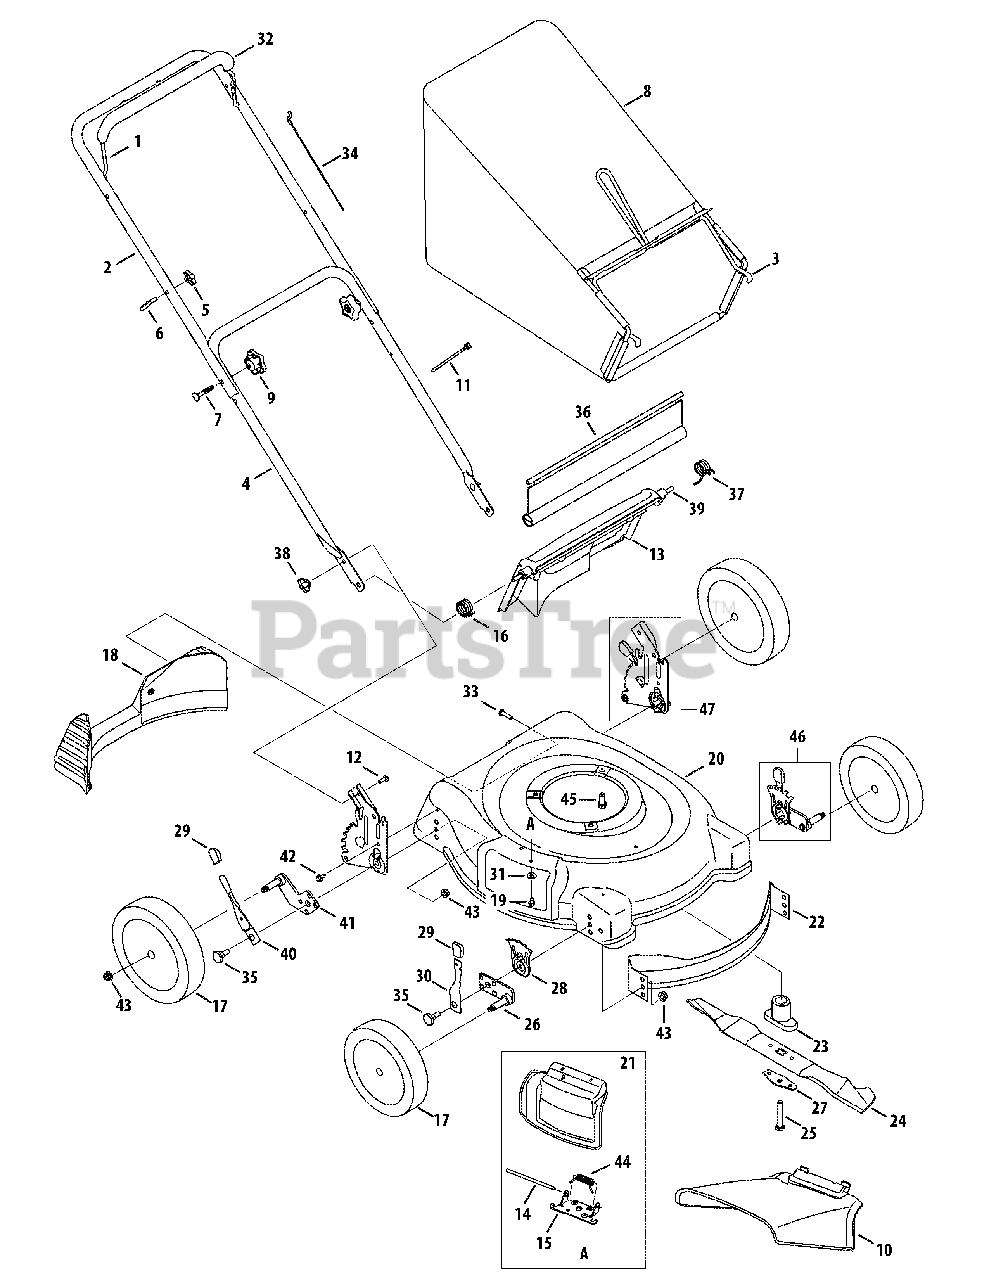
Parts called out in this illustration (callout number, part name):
6	Rope Guide
7	Carriage Bolt ,5/16-18 x 2
8	Grass Bag
9	Hand Knob
10	Side Chute
11	Cable Tie
12	Carriage Bolt ,1/4-20
13	Rear Discharge Door
14	Hinge Pin
15	Deflector Chute Adaptor
16	Torsion Spring - RH
17	Wheel
18	Rear Baffle
19	Screw, 1/4-20 x .500
22	Front Baffle
23	Blade Adapter, 25mm x 2.15
23	Blade Adapter, #6 x 2.15
24	Mulching Blade
25	Hex Screw , 3/8-24 x 2.5
26	Pivot Arm Assy RH (8" wheel)
26	Pivot Arm Assy LH (8" wheel)
27	Blade Bell Support
28	Front Adjustment Plate
29	Adjustment Lever Knob
30	Spring Lever Assembly
31	Bell Washer
32	Bail Cover
33	Screw, 1/4-15 x 1.000
34	Control Cable 40"
35	Shoulder Screw
36	Trailshield
37	Torsion Spring - LH
38	Wing Nut, 1/4-20
39	Rear Door Pivot Rod
40	Spring Lever
41	Pivot Arm Assembly - RH
41	Pivot Arm Assembly - LH
43	Flange Lock Nut, 3/8-16
44	Torsion Spring
45	TT Sems Screw, 3/8-16 x 1.0
46	Ht. Adj. Assy. Front LH (8" wheel)
46	Ht. Adj. Assy. Front RH (8" wheel)
47	Rear Handle Bracket Assy. - LH
